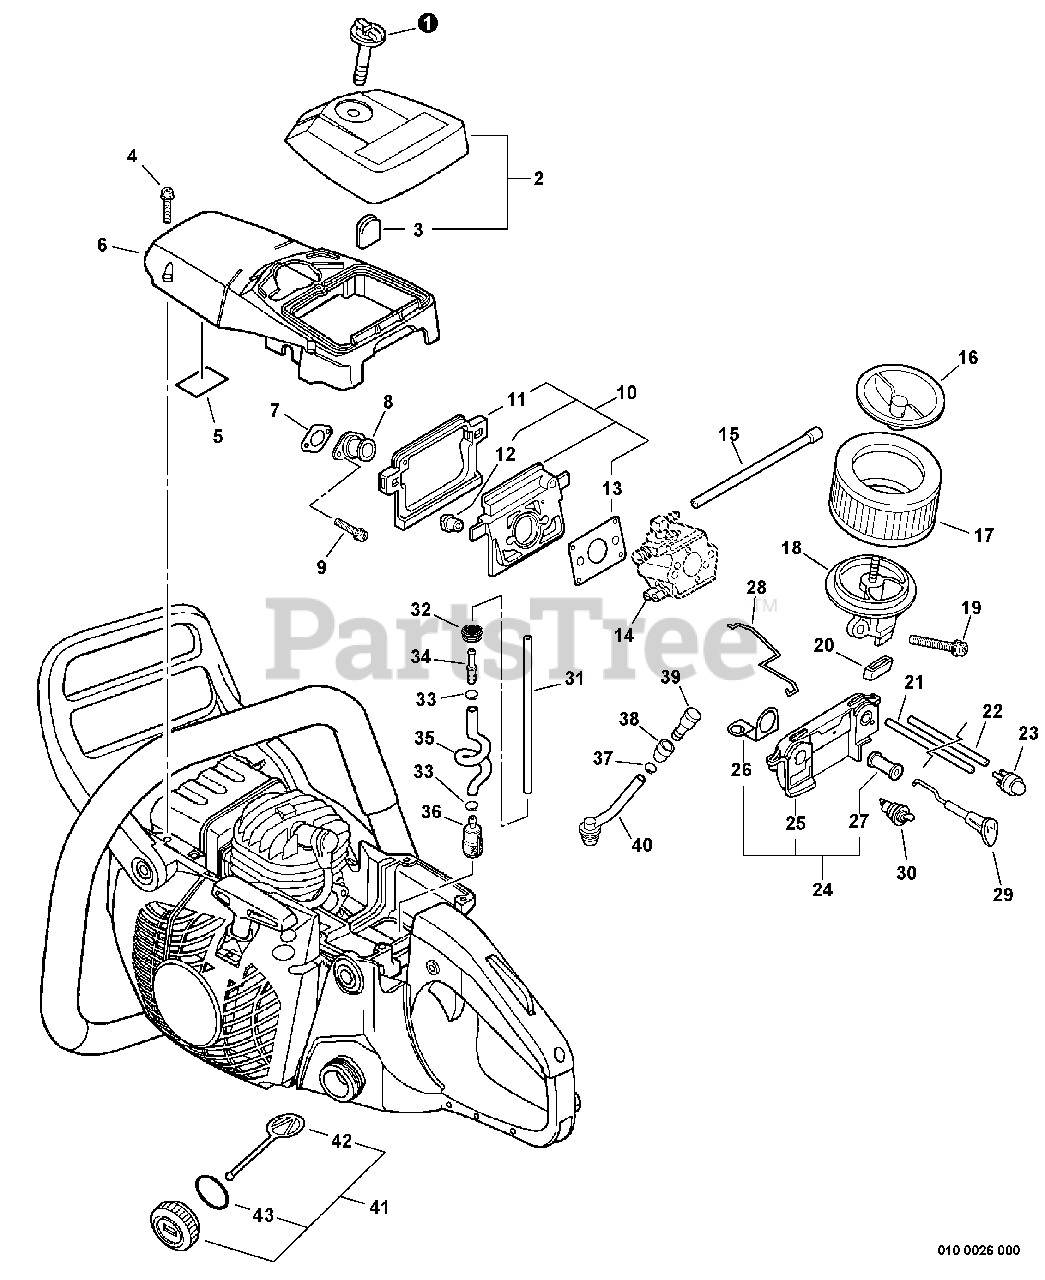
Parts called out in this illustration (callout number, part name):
1	THUMBSCREW
2	COVER ASSY, AIR FILTER
4	SCREW 5×25
5	SHIELD, HEAT
6	COVER, ENGINE
7	GASKET, INTAKE
8	ADAPTOR, INTAKE
9	SCREW 5×12
10	INSULATOR KIT, INTAKE
11	CUSHION
13	GASKET, INTAKE
14	CARBURETOR
15	PIPE, IMPULSE 3×5×110
16	CAP, AIR FILTER
17	FILTER, AIR
18	MOUNT, AIR FILTER
19	BOLT 5×50
21	PIPE, PURGE 2.5×5×140
22	PIPE, PURGE 2.5×5×140
23	BULB, PURGE
24	BRACKET KIT, SWITCH
25	BRACKET, SWITCH
26	TERMINAL, SWITCH
27	GROMMET, CHOKE
28	ROD, THROTTLE
29	ROD, CHOKE
30	SWITCH, ON-OFF
31	PIPE, FUEL
32	GROMMET, FUEL
33	CLIP Ø6.5 MM
34	CONNECTOR, PIPE Ø5ר3.5
35	PIPE, FUEL 3×6×56 BLACK
36	FILTER, FUEL
37	CLIP Ø6.5 MM
38	HOLDER, VENT
39	VENT ASSY
40	GROMMET, W/VENT PIPE 3×6×105
41	CAP ASSY, FUEL
42	CONNECTOR, CAP L= 60 MM
43	O-RING 22
